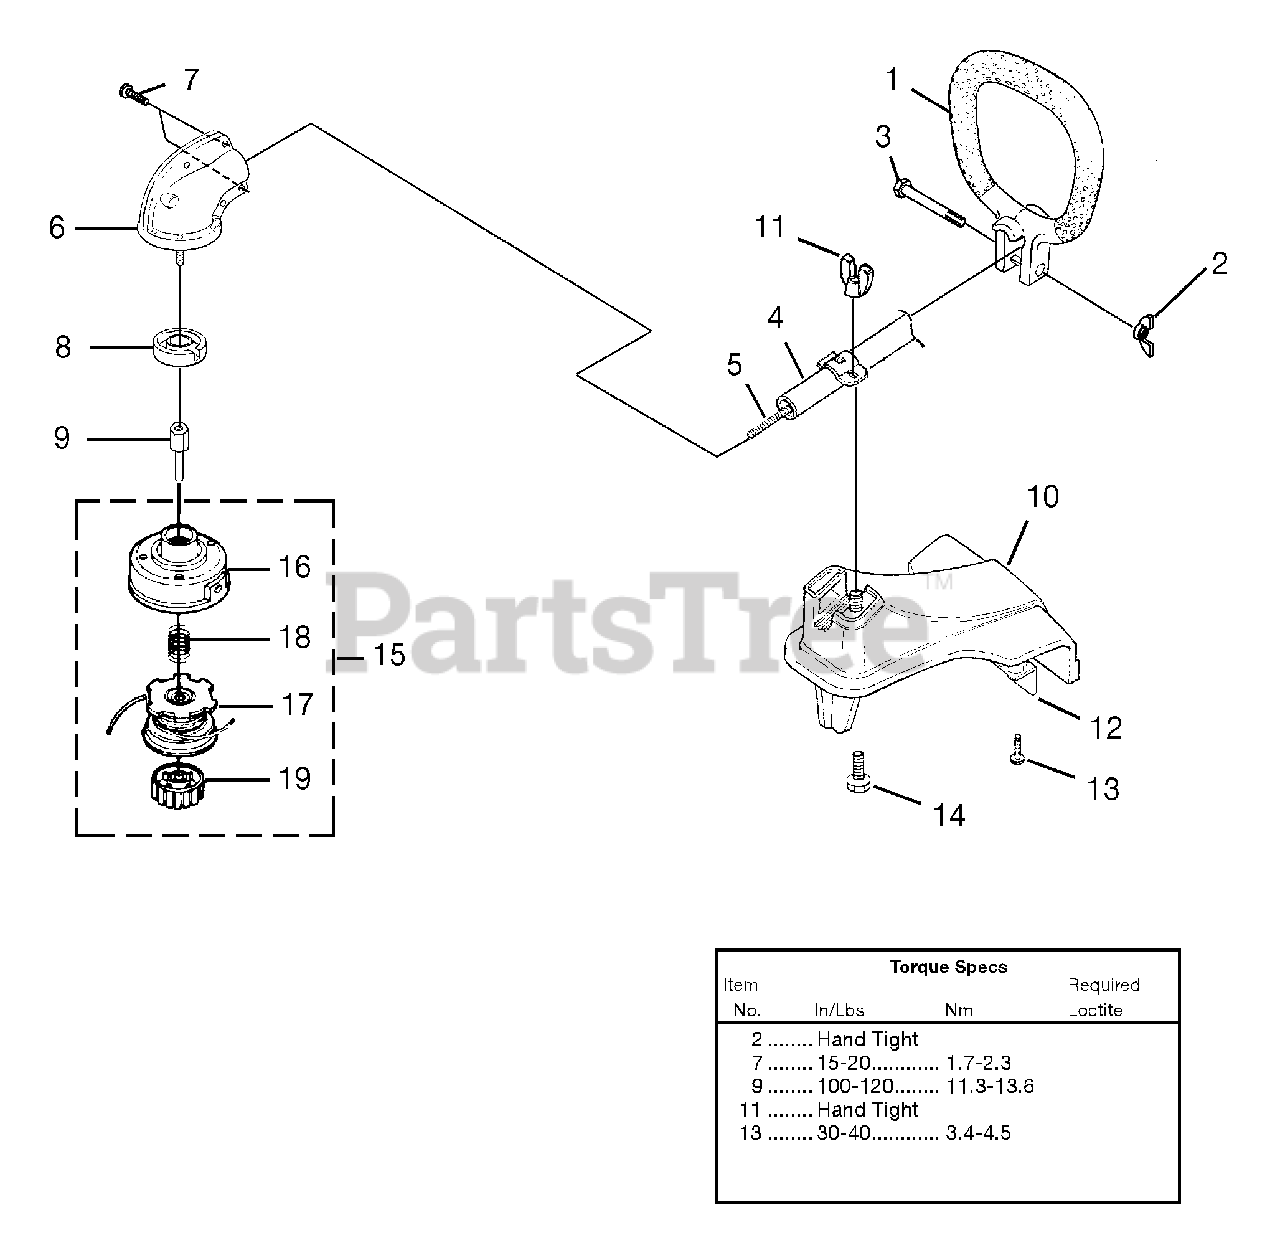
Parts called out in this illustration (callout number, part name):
1	HANDLE-Front
2	NUT-Wing, Washer Faced (1/4-20)
3	SCREW-Cap Hex Hd. (1/4-20 x 2")
4	DRIVESHAFT HOUSING ASSY.
5	SHAFT-Flexible
6	GEARHEAD
7	Screw, Taptite Hex Hd. (10-24 x 1/2")
8	WASHER-Flanged
9	ADAPTER-Shaft
10	GRASS DEFLECTOR KIT
11	WING NUT
12	BLADE-Cut-off
13	SCREW-Mach. Hex Hd. (10-24 X 3/8")
14	SCREW-Square Head
15	STRINGHEAD-Complete (.080" Line)
16	HOUSING & EYELET (Dual Line)
17	SPOOL & STRING (.080" Line)
18	SPRING-Compression
19	RETAINER-Spool (RH Thread, Black)
